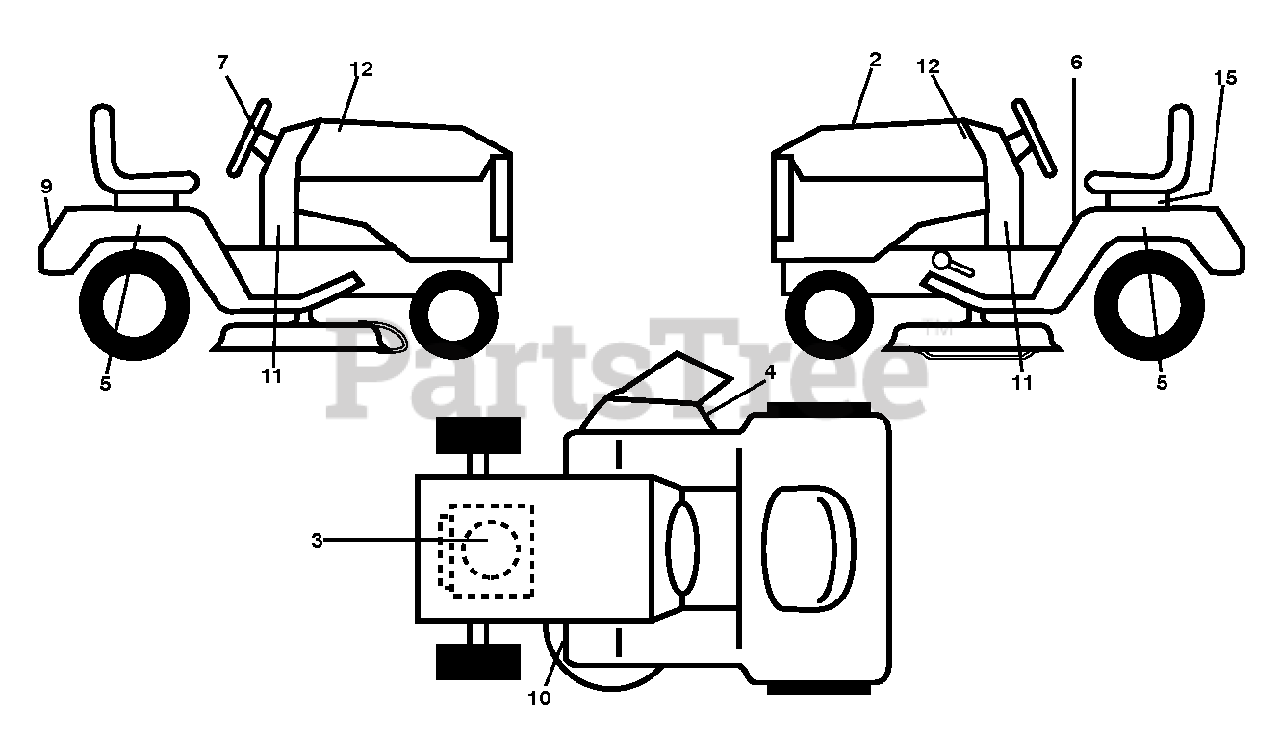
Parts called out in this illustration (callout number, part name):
2	DECAL.RPL.PMST.42C.BS.175.STL
3	DECAL.ENGINE.BS.14.5.PB.278975
4	DECAL.WARN.KEEP.HAND.AWAY
5	DECAL.FEND.RH/LH.SET.6S.POULAN
6	Fender Warning Decal, English
7	DECAL.WHEEL.STRG.STDHRS.POULAN
9	DECAL.FEND.POULAN.2010
11	DECAL.DASH.LOWER.145/38.11POU
12	DECAL.HOOD.ALPHA.RH/LH.POULAN
15	DECAL BTRY SYMBOLS
